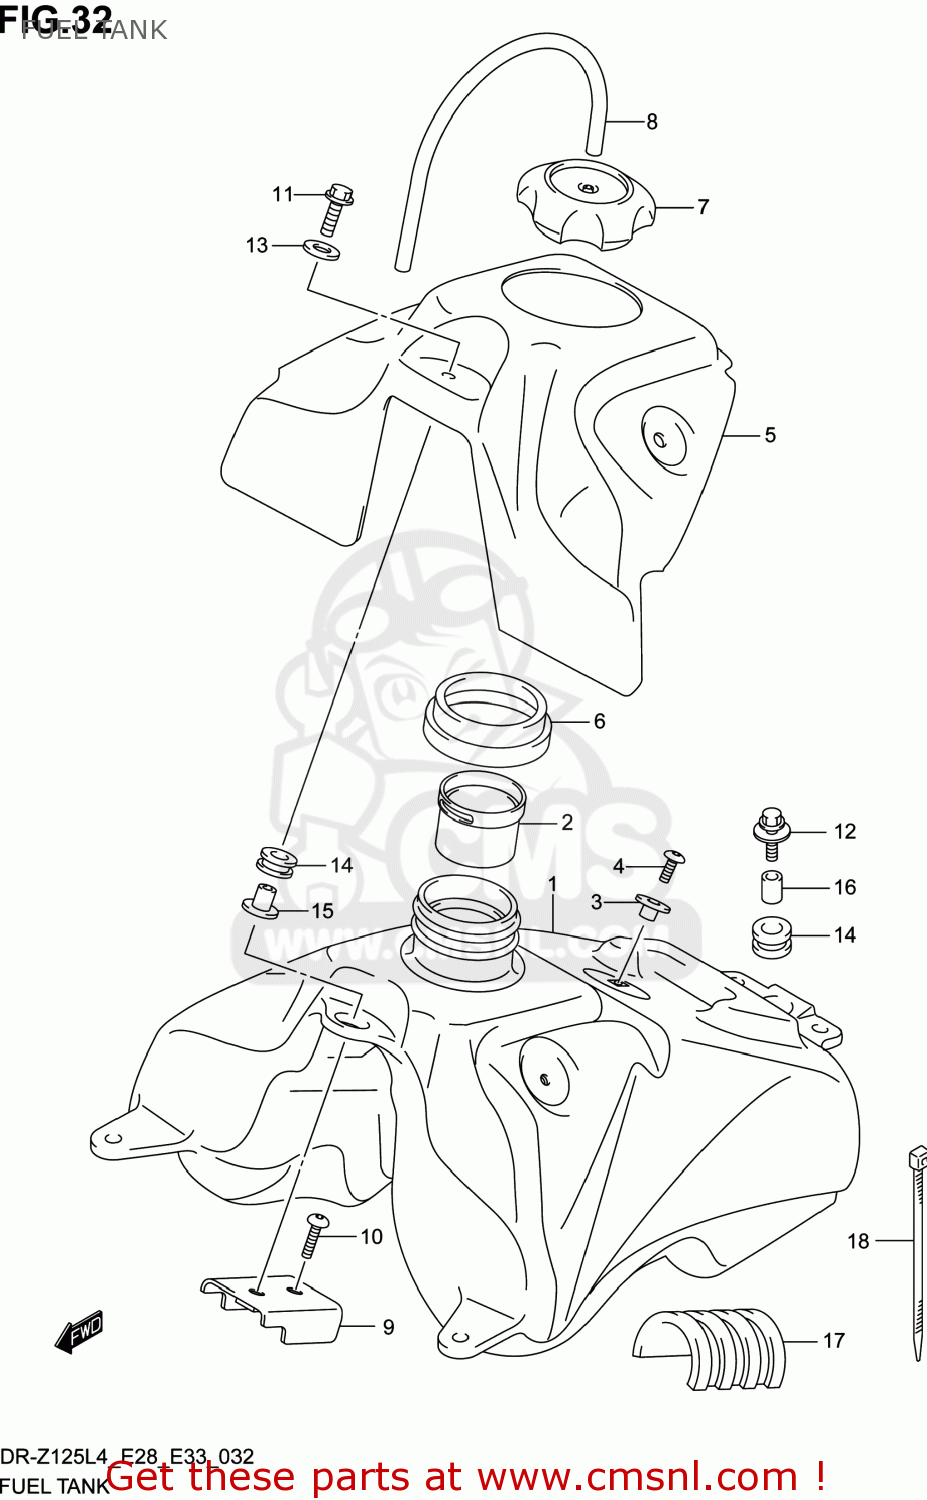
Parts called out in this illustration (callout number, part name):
1	TANK,FUEL
2	TUBE,FILLER INLET
3	HOOK,SEAT FR
4	BOLT(6X20)
5	COVER,FUEL TANK UPR
6	RUBBER,FUEL TANK INLET
7	CAP ASSY,FUEL TANK FILLER
8	HOSE(5X8.2X600)
9	BRACKET,FUEL TANK UPR
10	SCREW(6X10)
11	BOLT
12	BOLT(6X25)
13	WASHER(6.5X24X1.6)
14	CUSHION,FUEL TANK
15	WASHER,FUEL TANK FR
16	SPACER(6.5X10X14)
17	CUSHION,FUEL TANK
18	CLAMP(L:300)
